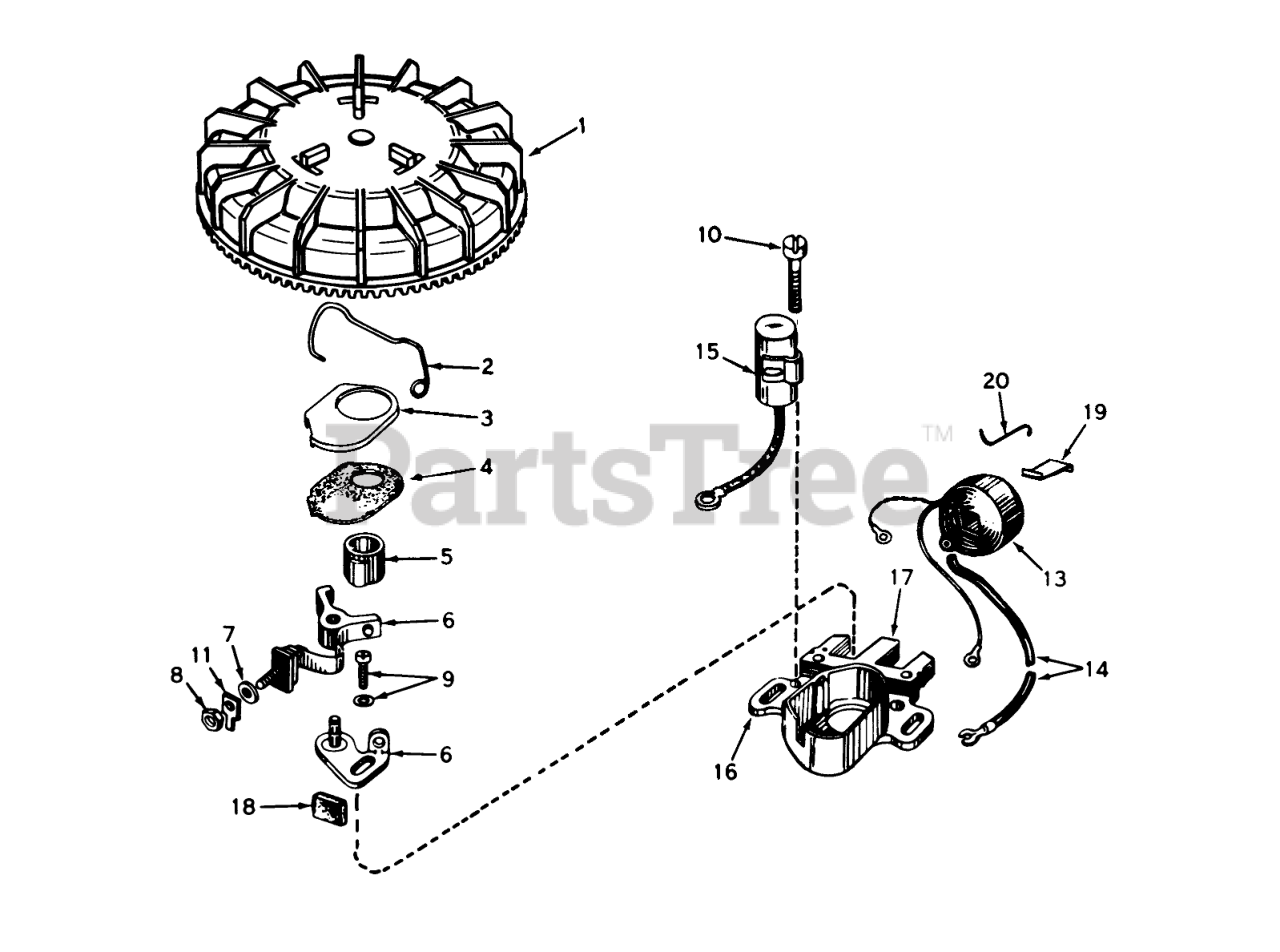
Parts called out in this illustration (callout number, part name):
1	Flywheel (Incl. Ref. #3 & 4)
2	Spring Breaker Box
3	Cover-Dust
4	Gasket, Dust Cover
5	Cam, Breaker
6	Breaker Assy.
9	Breaker Screw
10	Condenser Screw
11	Terminal, Ground
13	Coil Assembly (Incl. Ref.#14)
14	Wire, Lead
15	Condenser
16	Core & Plate
17	Stator Assembly (Incl . Ref.#2, 3, 4, 6 thru 16,18,19 & 20)
18	Felt,Cam Wiper
19	Spring Coil Wedge
20	Clip, Coil
